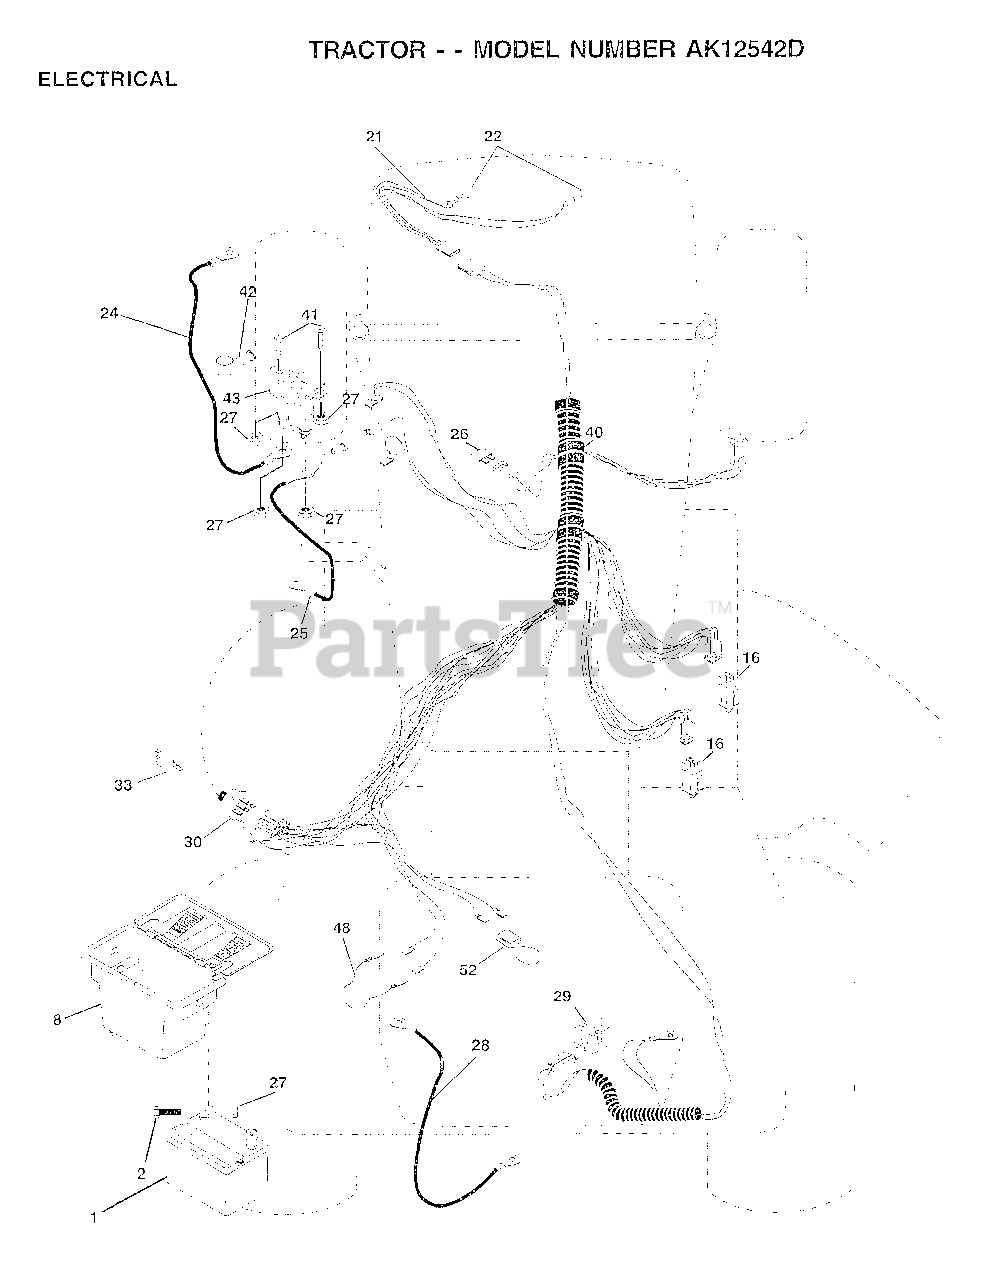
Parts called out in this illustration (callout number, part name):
2	BOLT LT
8	"CASE,BATTERY.MECH"
16	SWITCH INTERLOCK
21	HARNESS.ASM.LIGHT W/4152J
22	HEADLAMP BULB
24	"CABLE T, BATTERY"
25	CABLE.BTRY.6GA.RD
26	FUSE.15 AMP
27	NUT
28	CABLE T
29	SWITCH SEAT
30	SWITCH.IGN.
33	KEY MLD GEN DELTA
40	HARNESS IGN
41	BOLT HXHD FIN
48	ADAPTER AMMETER
52	PROTECTION LOOP
